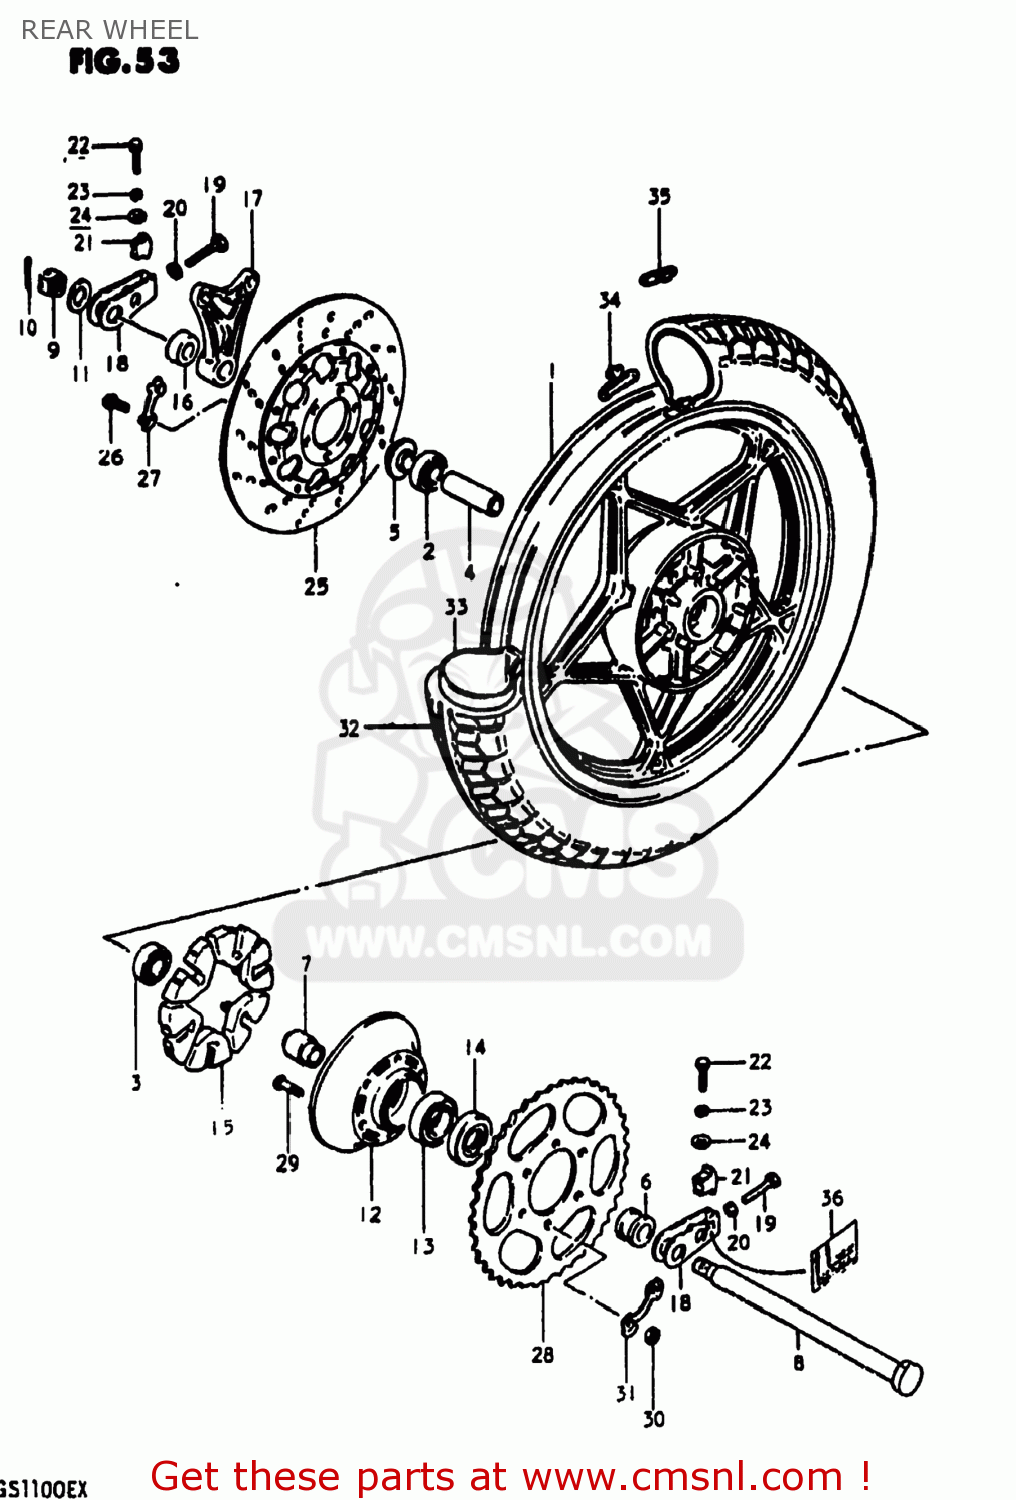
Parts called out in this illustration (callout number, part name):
1	WHEEL,REAR
2	BEARING WHEEL REAR(20X47X14)
3	BEARING, LH
4	SPACER(20.5X28X88)
5	SPACER,REAR AXLE
6	SPACER(20X33X28.3)
7	SPACER,REAR HUB BEARING
8	AXLE,REAR
9	NUT 18MM
10	PIN,COTTER
11	WASHER(19X34X4)
12	DRUM,REAR SPROCKET MOUNT
13	BEARING
14	SEAL,OIL(33X62X7)
15	ABSORBER,REAR HUB SHOCK
16	SPACER(20X38X12)
17	BRACKET,RR,CALIPER
18	ADJUSTER,CHAIN
19	BOLT
20	NUT
21	SUPPORTER,CHAIN ADJUST
22	BOLT
23	LOCK WASHER
24	WASHER
25	DISC,RR BRAKE
26	BOLT(8X30)
27	WASHER
28	SPROCKET,REAR
29	BOLT
30	NUT
31	WASHER
32	TIRE 4.50V17
33	TUBE ASSEMBLY,WHEEL,INNER
34	BALANCER,WHEEL
35	BALANCER,WHEEL
36	LABEL,CHAIN WEAR INDICATOR
